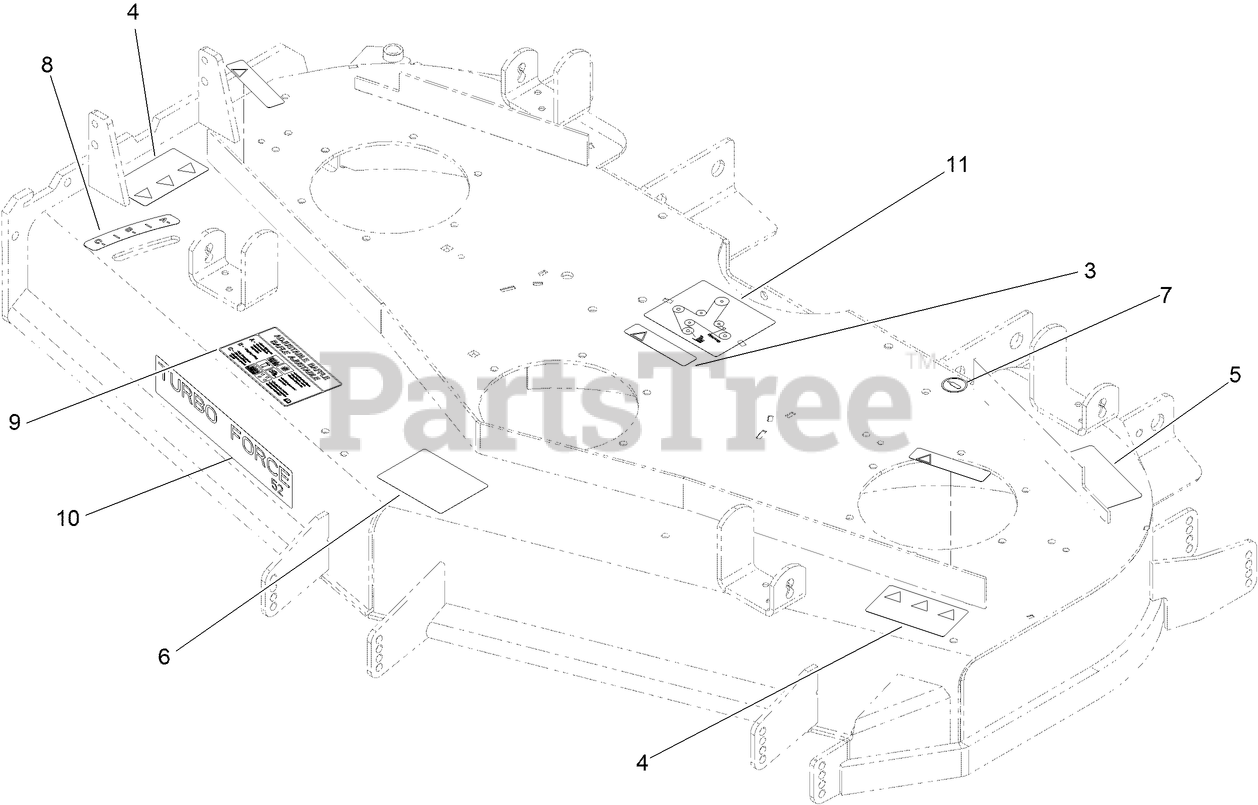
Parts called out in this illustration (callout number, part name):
3	DECAL-WARNING
4	DECAL-DANGER
5	DECAL-TORQUE, BLADE BOLT
6	DECAL-ANTI SCALP
7	DECAL-GREASE
8	DECAL-SETTING, BAFFLE
9	DECAL-ADJUSTMENT, BAFFLE
11	DECAL-ROUTING, BELT
